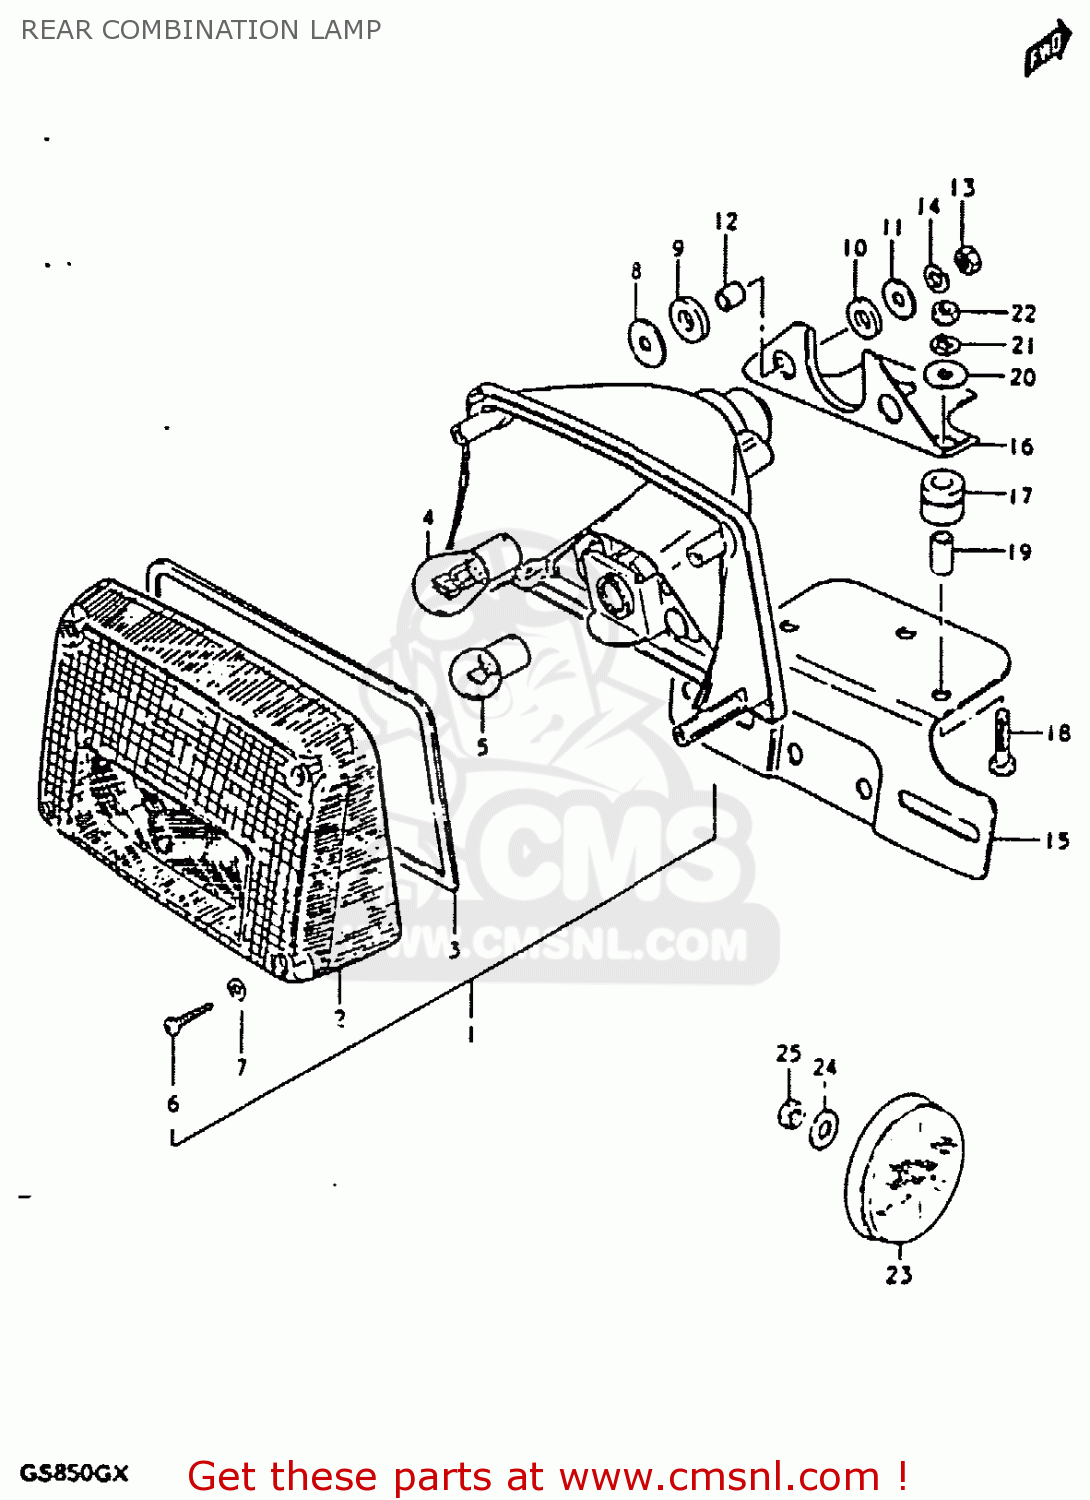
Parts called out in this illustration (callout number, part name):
1	LAMP ASSEMBLY,REAR COMBINATION
2	LENS
3	GASKET (NAS)
4	BULB(12V23W)
5	BULB
6	BOLT
7	GASKET (NAS)
8	WASHER
9	CUSHION
10	CUSHION
11	WASHER(6,5X22X1.6)
12	SPACER(6.1X9X7.5)
13	NUT
14	LOCK WASHER
15	BRACKET, LICENCE PLATE
16	BRACKET,LICENSE PLATE
17	CUSHION, BRACKET
18	BOLT
19	SPACER (6.4X9X15.5)
20	WASHER
21	LOCK WASHER
22	NUT
23	REFLEX REFLECTOR,RR
24	WASHER
25	NUT
